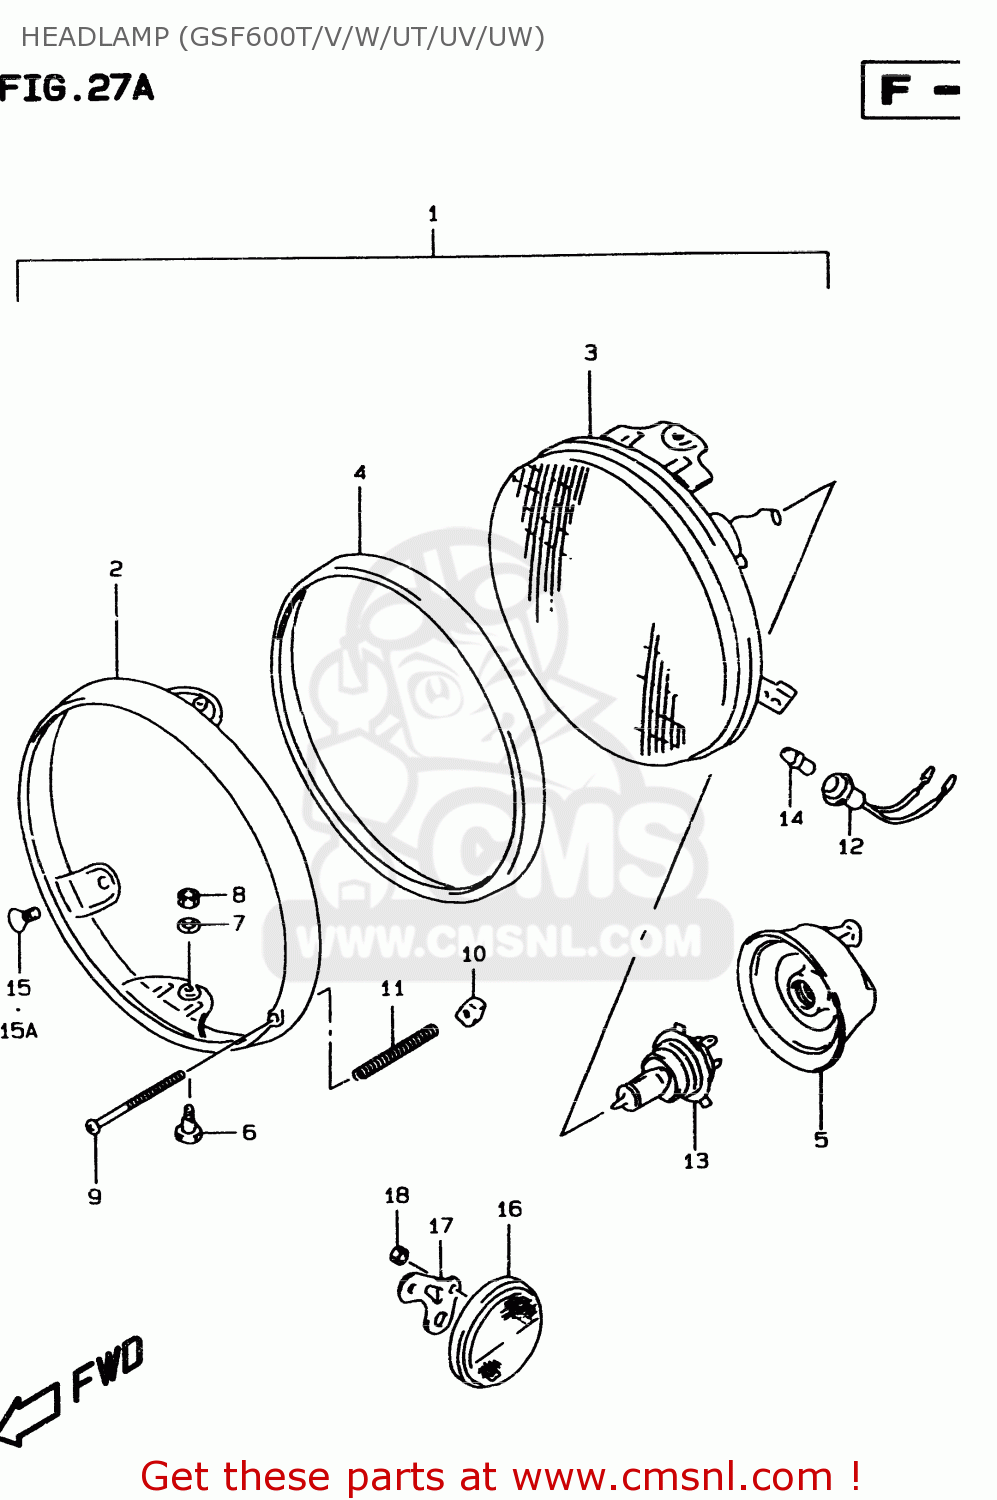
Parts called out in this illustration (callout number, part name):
1	HEADLAMP ASSY
2	RIM,HEADLAMP
3	LAMP UNIT
4	RING
5	COVER,SOCKET
6	H/LAMP LENS UNIT FITING SCRE
7	WASHER,LOCK
8	NUT
9	SCREW
10	NUT
11	SPRING,ADJUSTING
12	SOCKET,PARKING LAMP
13	BULB(12V60/55W,H4)
14	BULB(12V4W)
15	SCREW
15A	SCREW(5X12)
16	REFLECTOR,REFLEX FR
17	BRACKET,FR SIDE REFLECTOR
18	NUT
